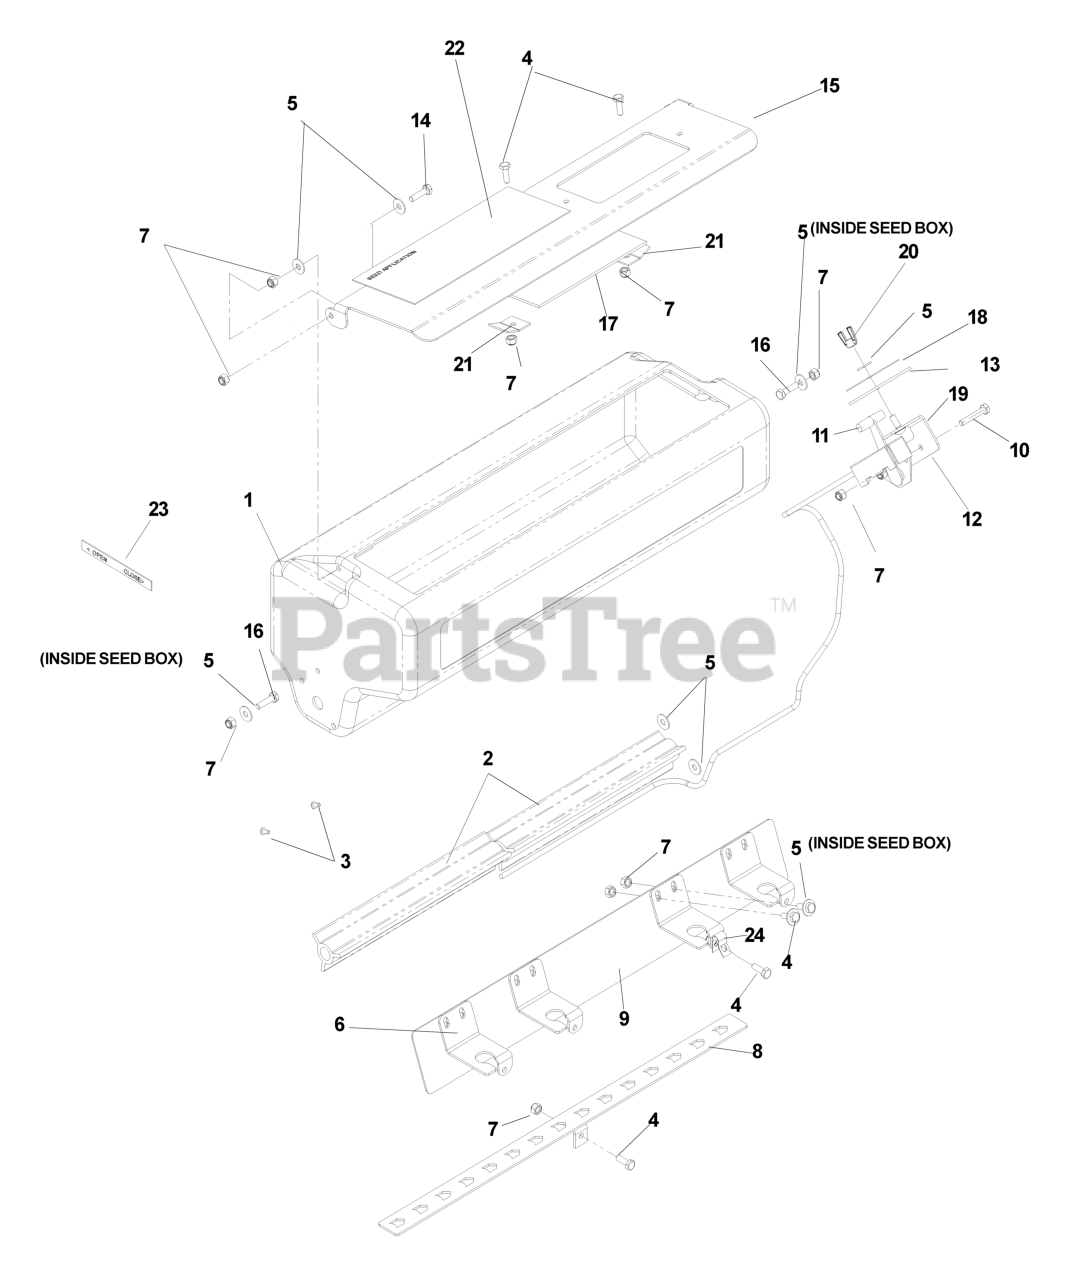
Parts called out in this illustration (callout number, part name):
1	SEED BOX CHARCOAL GREY
3	HR STRIP, 1/8 X 1
4	HCS 1/4C X 3/4 HCS
5	WASHER 1/4 FLAT
7	NUT.1/4-20.HEX.NYLOC.ZD
10	SCW 1/4-20 X 1-1/2 HEX
11	PUSH/PULL ASSY CONTROL
14	HCS 1/4C X 1
15	SEED DOOR ORANGE
16	HCS 1/4 X 1
17	SEED WINDOW
18	DECAL, SEED DIAL
19	RHSNB 1/4C X 3/4
20	WING NUT 1/4
21	WINDOW CLIP
22	DECAL, SEED APPL
23	DECAL, OPEN/CLOSE
24	PUSH PULL CONTROL CLAMP
